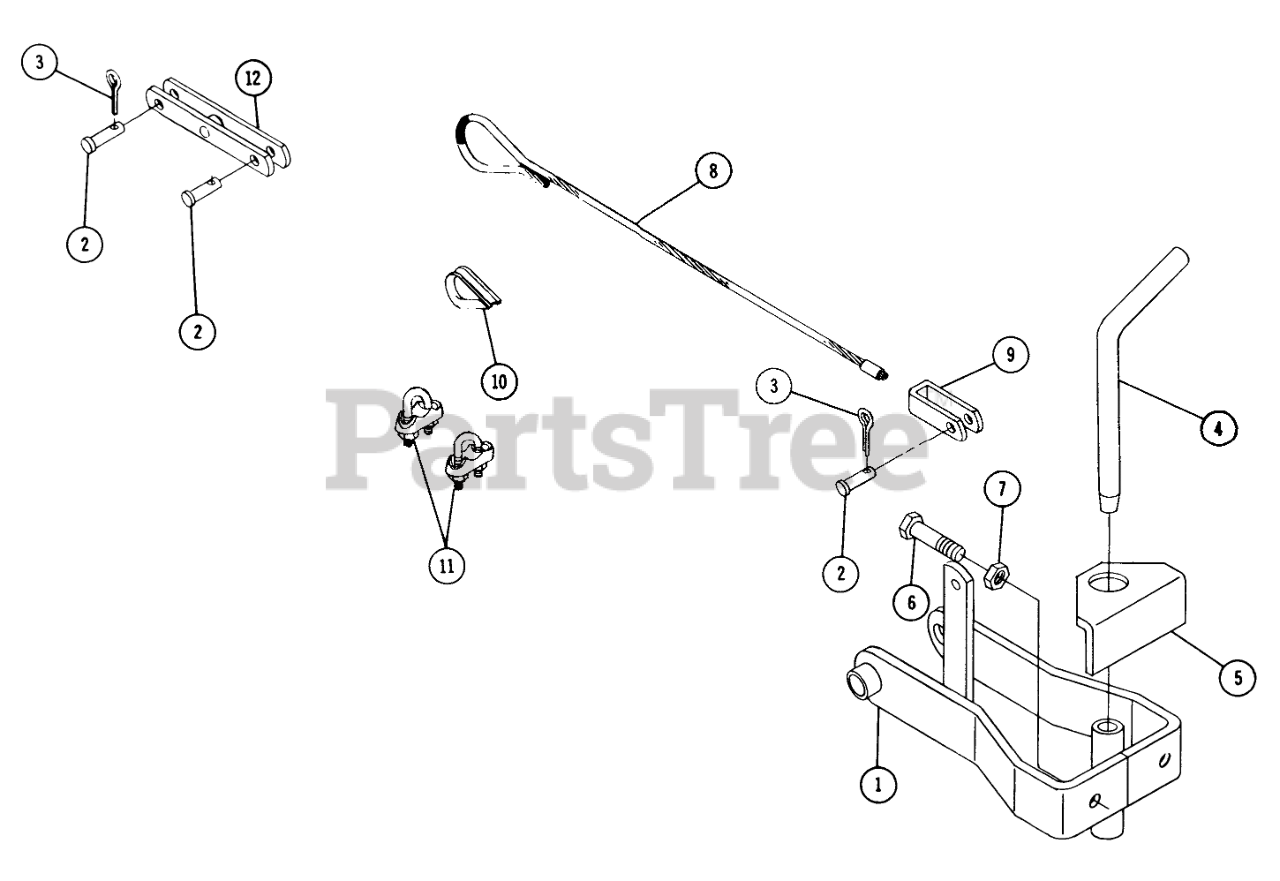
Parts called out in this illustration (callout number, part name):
1	Hitch Ass-y.
2	Pin
3	Cotter Pin
4	Hitch Pin
5	PLATE ADJ HITCH R
6	Screw 1/2-13 x 2
7	Jam Nut
8	CABLE-LIFT LVR HITCH
9	Clevis
10	Thimble
11	U BOLT
12	ASSEMBLY CLEVIS
